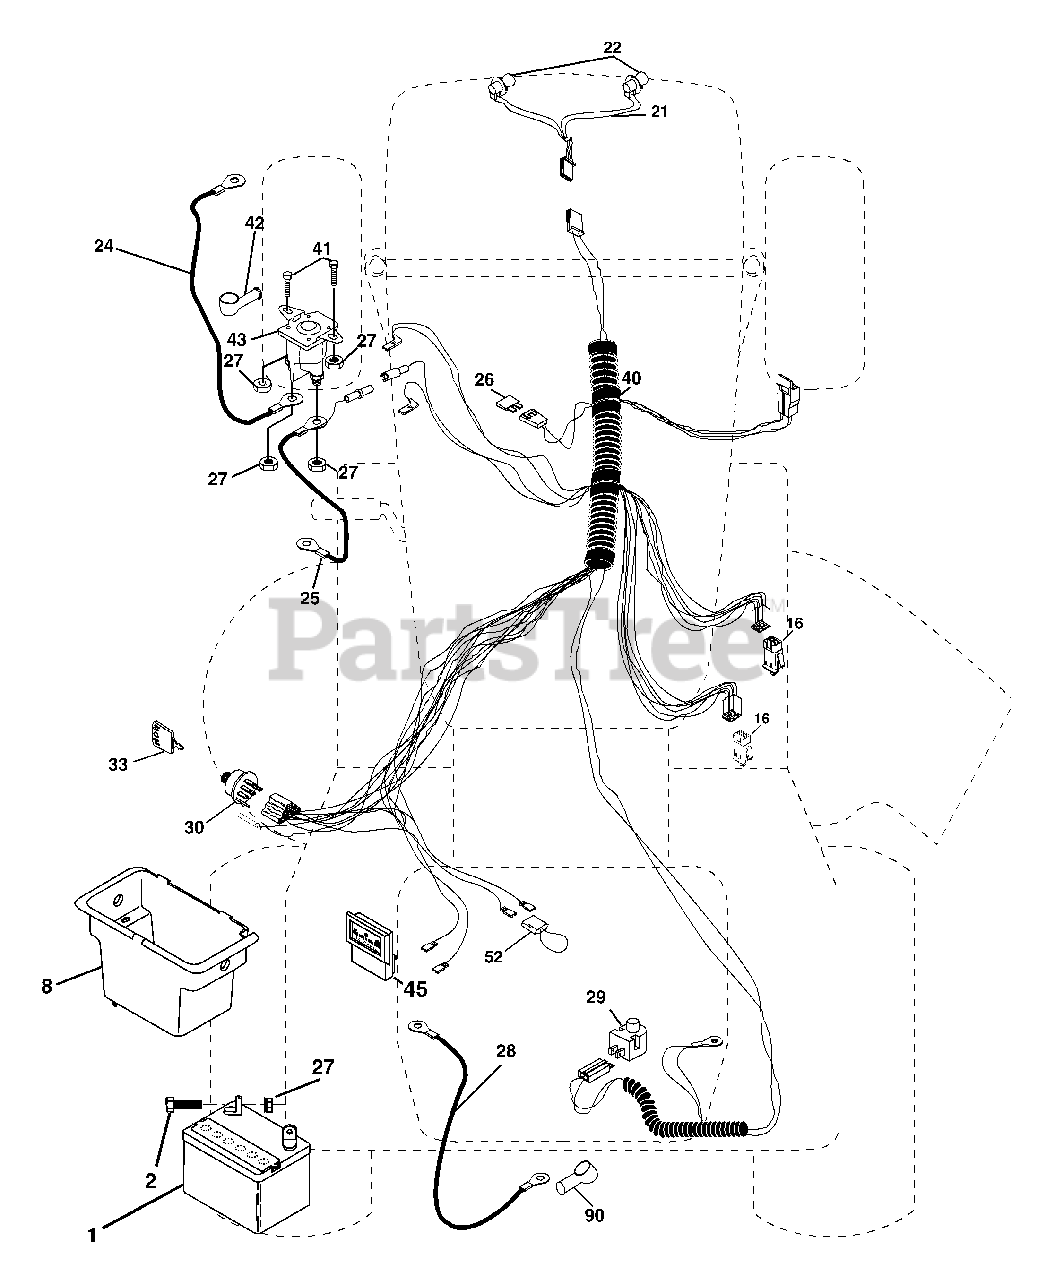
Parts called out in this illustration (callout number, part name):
1	Battery
2	Bolt Hex Hd 1/4-20 unc x 3/4
8	Box Battery
16	Switch Interlock
21	Harness Asm Light W/4152j
22	Bulb Light #1156
24	Cable Battery 6 Ga. 11" red
25	Cable Battery 6 Ga. 44" red w/16 wire
27	Nut Keps Hex 1/4-20 unc
28	Cable Ground 6 Ga 12" black
29	Switch Plunger Olive
30	Switch Ign Delta
33	Key Ign Molded Generic
40	Harness Ign.
41	Bolt Blk Fin Hex 1/4 - 20 x 1/2
42	Cover Terminal Red
43	Solenoid
45	Ammeter Rectangular
52	Protection Wire Loop
90	Cover Terminal Battery
